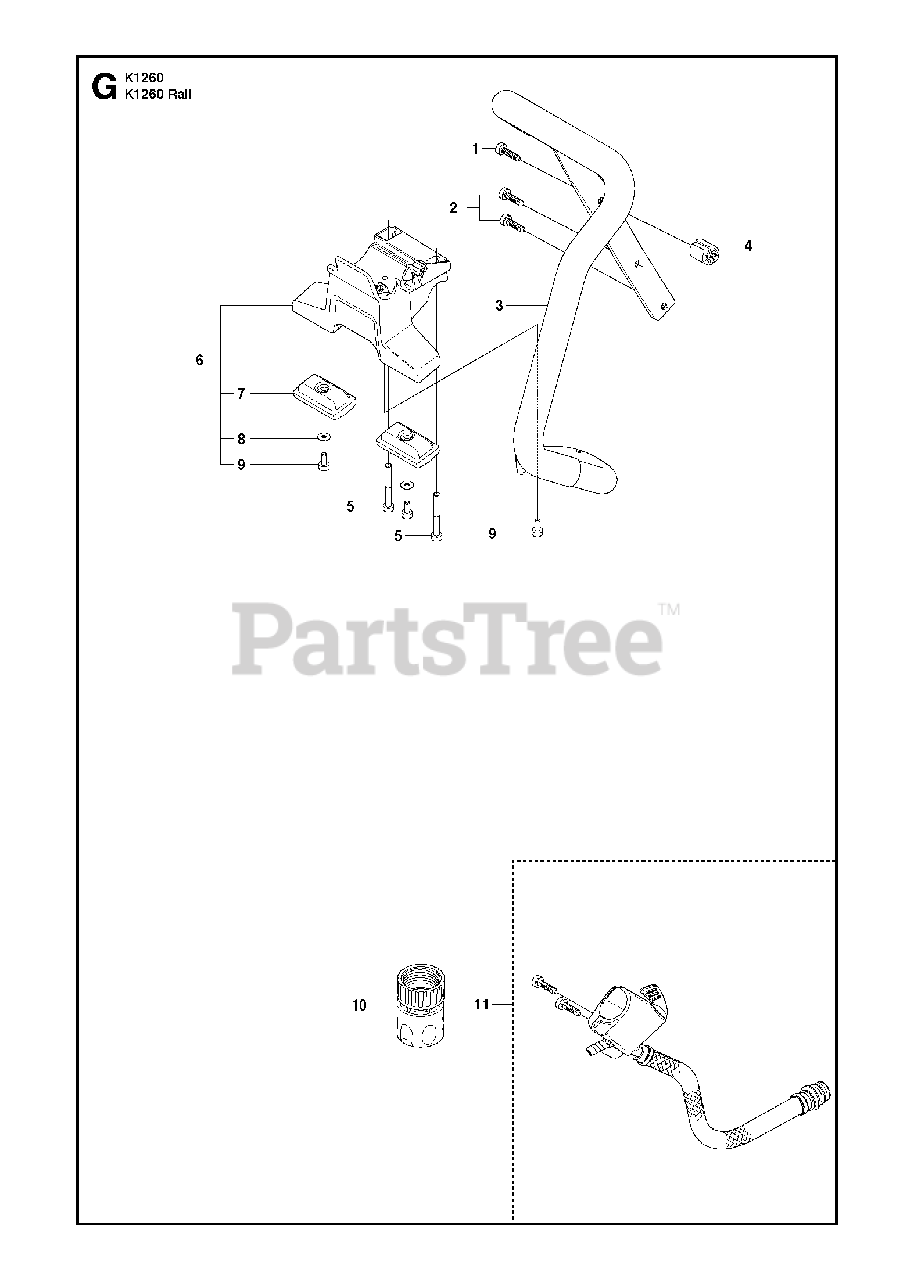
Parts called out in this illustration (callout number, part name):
1	SCREW ITXSCM
2	SCREW ITXSCT
3	HANDLE
4	ANTIVIBRATION ELEMENT
5	SCREW ITXSCM
6	GROUND SUPPORTIncl. 7 - 9
9	SCREW ITXSCM
10	COUPLERUSA, Canada
